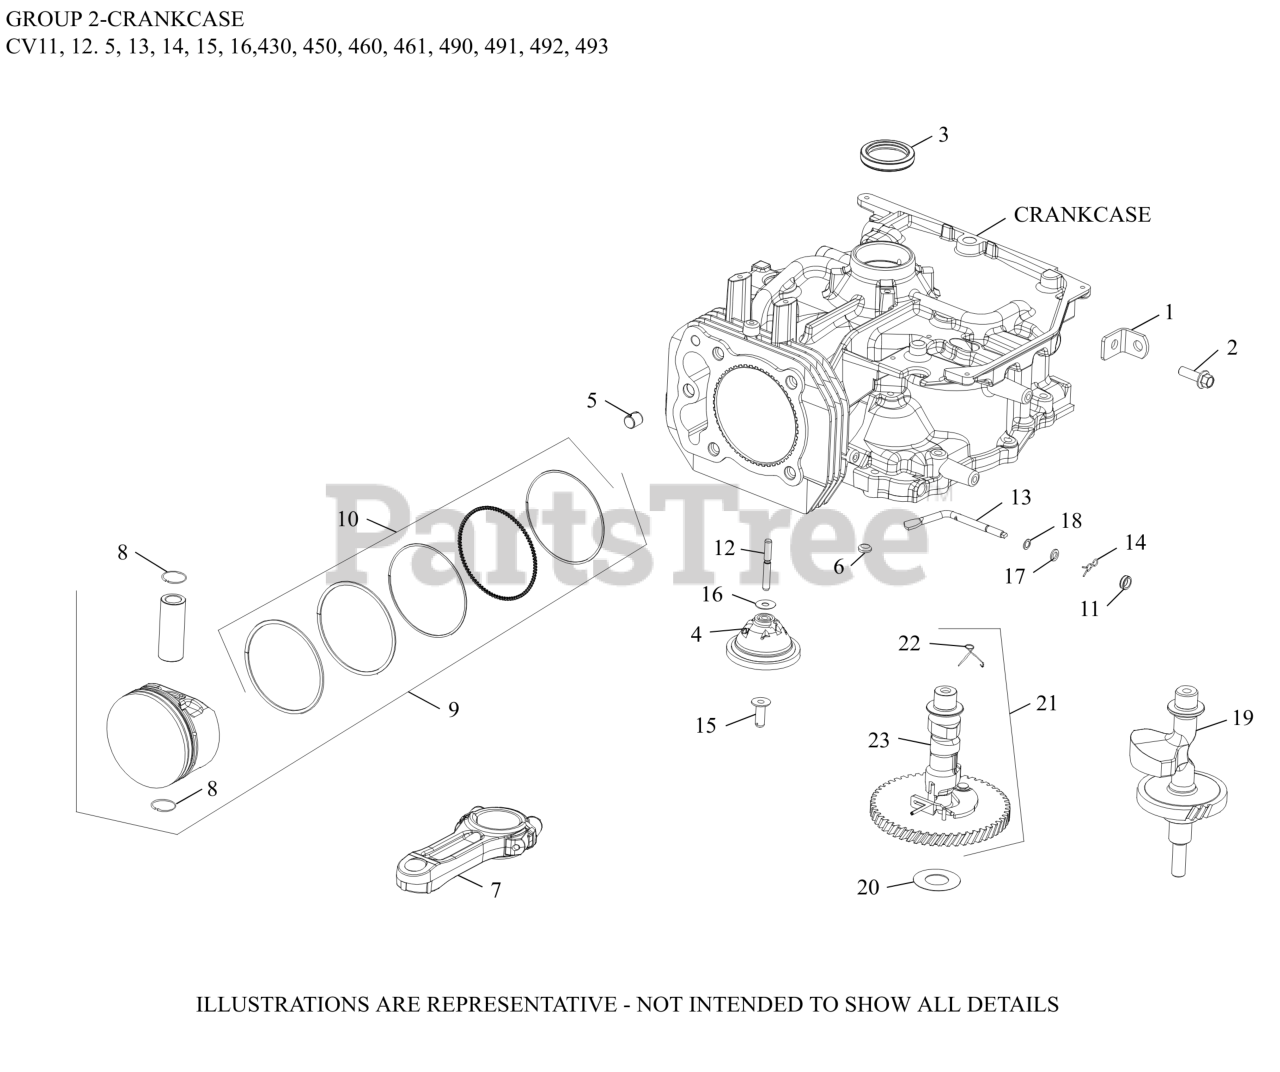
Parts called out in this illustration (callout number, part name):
2	SCREW, FLG M8X1.25X25
3	SEAL, OIL
4	GOVERNOR GEAR ASSEMBLY
5	PIN, LOCATING
6	PLUG, CUP
7	ROD, CONNECTING (STD)
7	ROD, CONNECTING (.25)
9	KIT, PISTON W/RING SET (STD)-(#DSC)
9	KIT, PISTON W/RING SET (.25)-DISC.
9	KIT, PISTON W/RING SET (.50)-DISC.
9	KIT, PISTON W/RING SET (.08)-DISC.
10	RING SET (STD & .08)
11	SEAL, GOVERNOR CROSS SHAFT
12	SHAFT, GOVERNOR GEAR
13	KIT, GOVERNOR CROSS SHAFT
14	CLIP, HITCH PIN
15	PIN, GOVERNOR REGULATING
16	WASHER, FLAT 6 MM
17	WASHER, FLAT 6 MM
18	WASHER, FLAT 1/4"
19	SHAFT, BALANCE
20	SHIM, CAMSHAFT (WHITE .028")
20	SHIM, CAMSHAFT (BLUE .03")
20	SHIM, CAMSHAFT (RED .032")
20	SHIM, CAMSHAFT (YELLOW .034")
20	SHIM, CAMSHAFT (GREEN .036")
20	SHIM, CAMSHAFT (GRAY .038")
20	SHIM, CAMSHAFT (BLACK .04")
21	KIT, CAMSHAFT ASSEMBLY-DISCONTINUED
22	SPRING, ACTUATING
NI	KIT, ROD BOLTS
